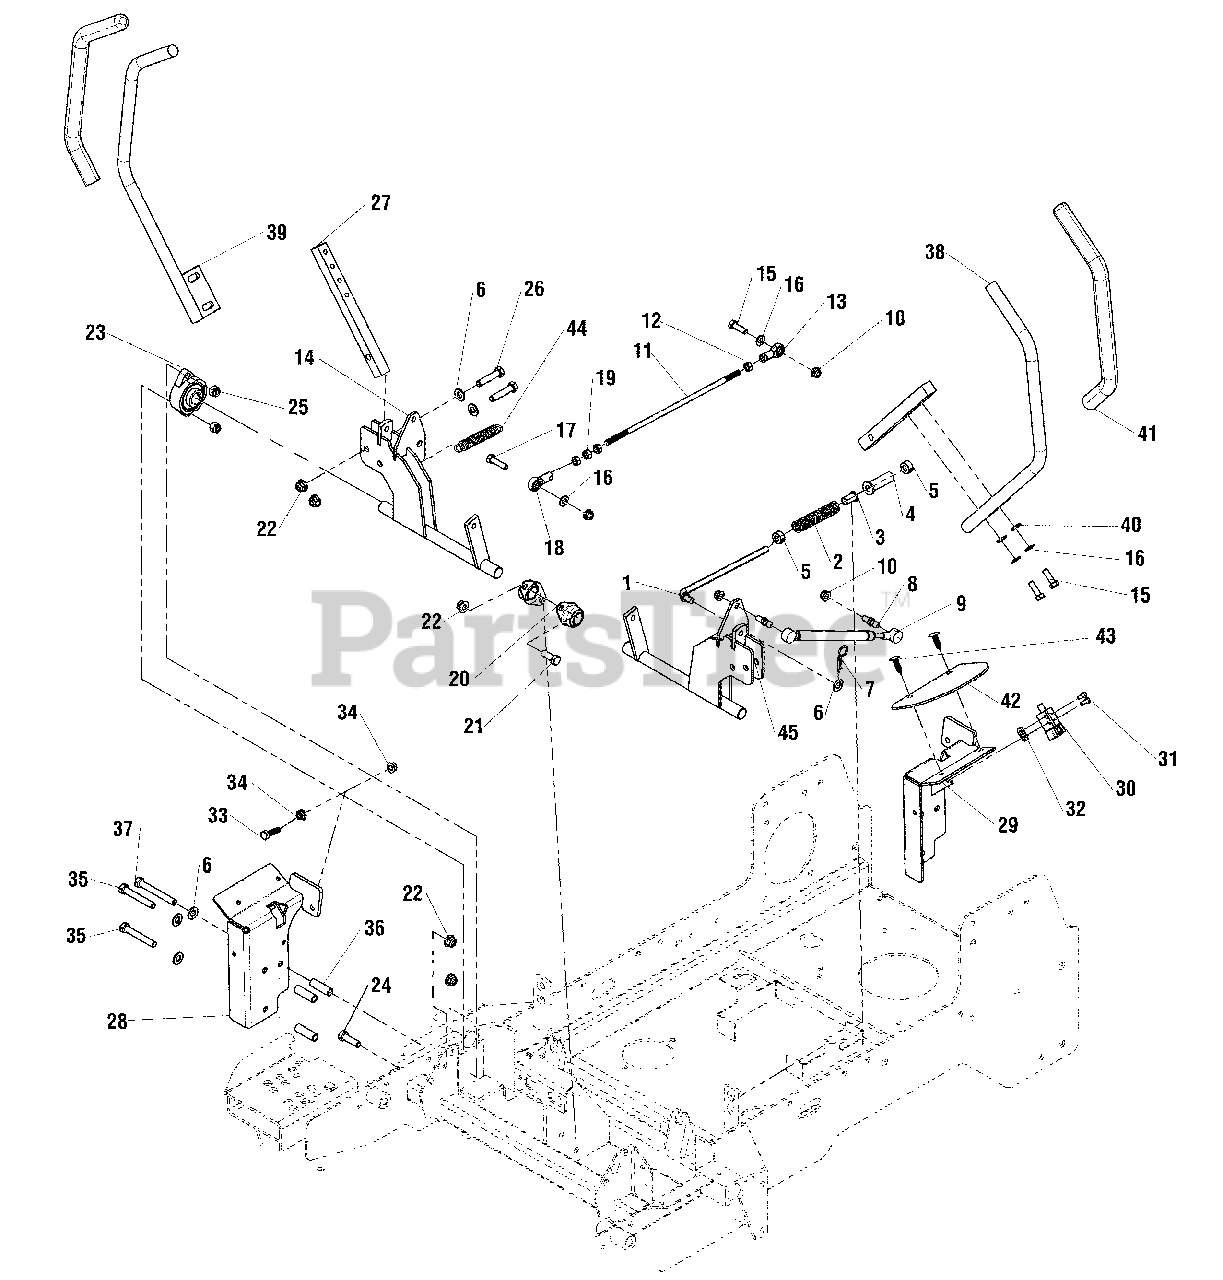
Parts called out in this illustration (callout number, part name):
1	ROD, NEUTRAL RETURN, CZ
2	SPRING, REVERSE RETURN
3	BUSHING, FLANGE 3/8ID X 7/8 LONG
4	FLANGED BUSHING, 3/8IDX.63ODX.8125FL
5	COLLAR, 3/8" Set
6	WASHER, 3/8 SAE
7	3/32 X 1-5/8 HAIR PIN CLIP
8	BALL STUD, 5/16 X .50,# PC-477-2)
9	DAMPENER, CONTROL,#(P6709/P3610)
10	NUT, 5/16-18 HEX NYLOCK FLANGE NUT
11	ROD, HYDRO LINKAGE
12	NUT, 5/16-24 HEX, LH
13	BALL JOINT 5/16-24 LH FEMALE STAMPED STL
14	SHAFT MTN CNTRL RH
15	BOLT, 5/16-18 X 1" GRD5 YZ
16	WASHER, 5/16" SAE
17	BOLT, 5/16-18 X 1-1/4" GD5 YZ
18	BALL JOINT 5/16-24 RH FEMALE STAMPED STL
19	NUT, Hex, 5/16-24
20	BEARING, BRONZE FLANGE, 3/4"
21	BOLT, 3/8-16 X 1" GD5 YZ
22	NUT, 3/8 - 16 HEX NYLOCK FLANGE
23	BEARING, FLANGE
24	BOLT, 3/8-16 X 1-1/4" GD5 YZ
25	NUT, Hex, Nylon Locking, 3/8-16
26	BOLT, 3/8-16 X 1-3/4" GD5 YZ
27	MOUNT, CONTROL ARM - BLK
28	WELD, NEUTRAL LOCK - RH - IS500Z - BLK
29	WELD, NEUTRAL LOCK - LH - IS500Z - BLK
30	SWITCH, Push Button, N.O . N.C, Double Pole, Grey
31	SCREW, #10-24 X 1/2" ROUND PHILLIPS
32	NUT, HEX, #10-24
33	BOLT, 5/16-18 X 1-1/8 GD5 CZ
34	NUT, 5/16-18 HEX SERRATED FLANGE (SMALL)
35	BOLT, 3/8-16 X 2-1/2" GD5 YZ
36	SPACER, .39 X .63 X 1.50, CZ
37	BOLT, 3/8-16 X 3" GD5 YZ
38	WELD, HANDLE MOTION CONTROL, LH - BLK
39	WELD, HANDLE MOTION CONTROL, RH - BLK
40	WASHER, 5/16 LOCK YZ
41	GRIP, FOAM, 3/4" ID, 16"" LONG
42	GUARD, RUBBER MOT CTRS - IS500Z
43	PUSH RIVET (TREE TYPE), BLACK
44	SPRING-EXT, .500 OD X 3.50 LG X .058 WR
45	SHAFT MTN CNTRL LH
